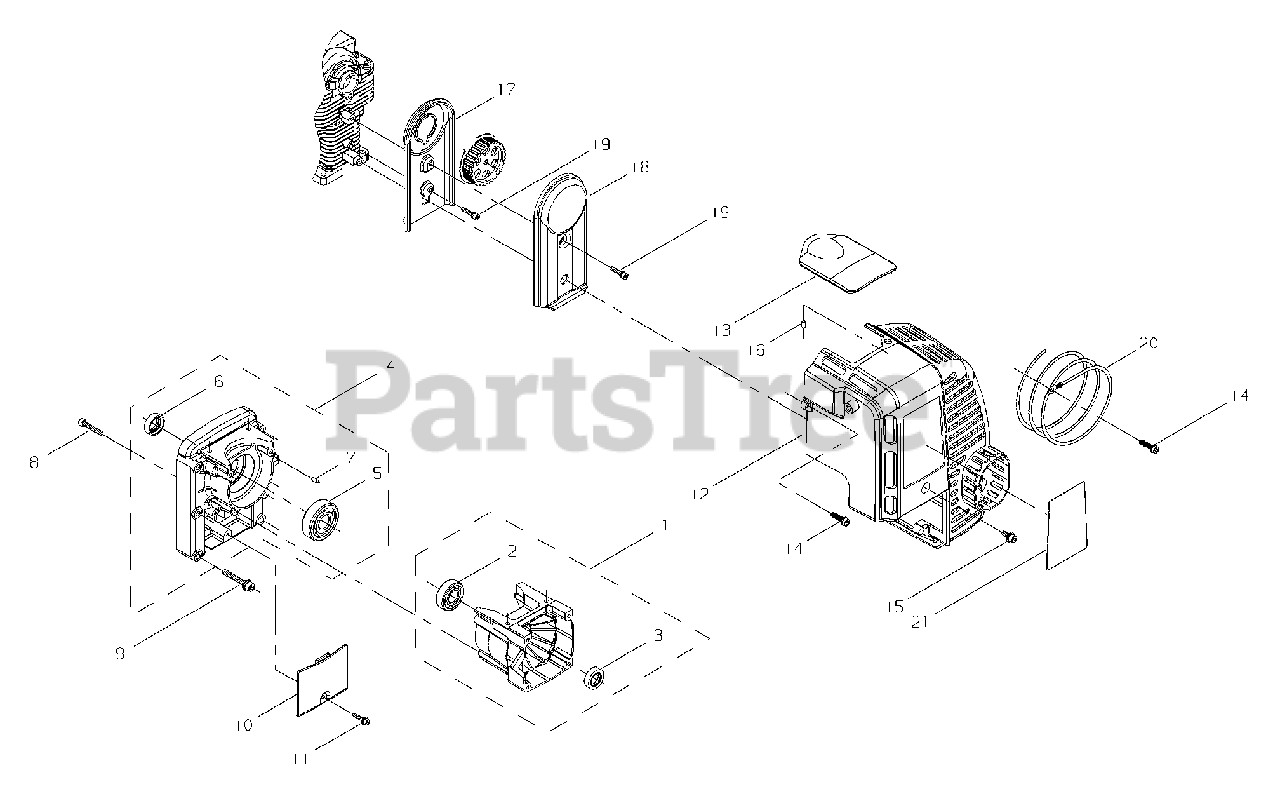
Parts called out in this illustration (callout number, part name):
1	CRANKCASE ASSY, S
2	BEARING, BALL 6202C3
3	SEAL, OIL 21
4	CRANKCASE ASSY, M
5	BEARING, BALL 6303 C3
6	SEAL, OIL 21
7	PIN, LOCATING Ø4×8
8	BOLT 5×30
9	BOLT, ADHESIVE M6×40
10	COVER, IGNITION COIL
11	BOLT M4×20
12	COVER, ENGINE
13	COVER, SPARK PLUG
14	BOLT M5×20
15	BOLT 5×14
16	PIN, LOCATING Ø4×8
17	CASE, BELT
18	COVER, BELT
19	BOLT M5×12
20	WIRE, STATIC DISCHARGE 1050 MM
21	LABEL, ID
